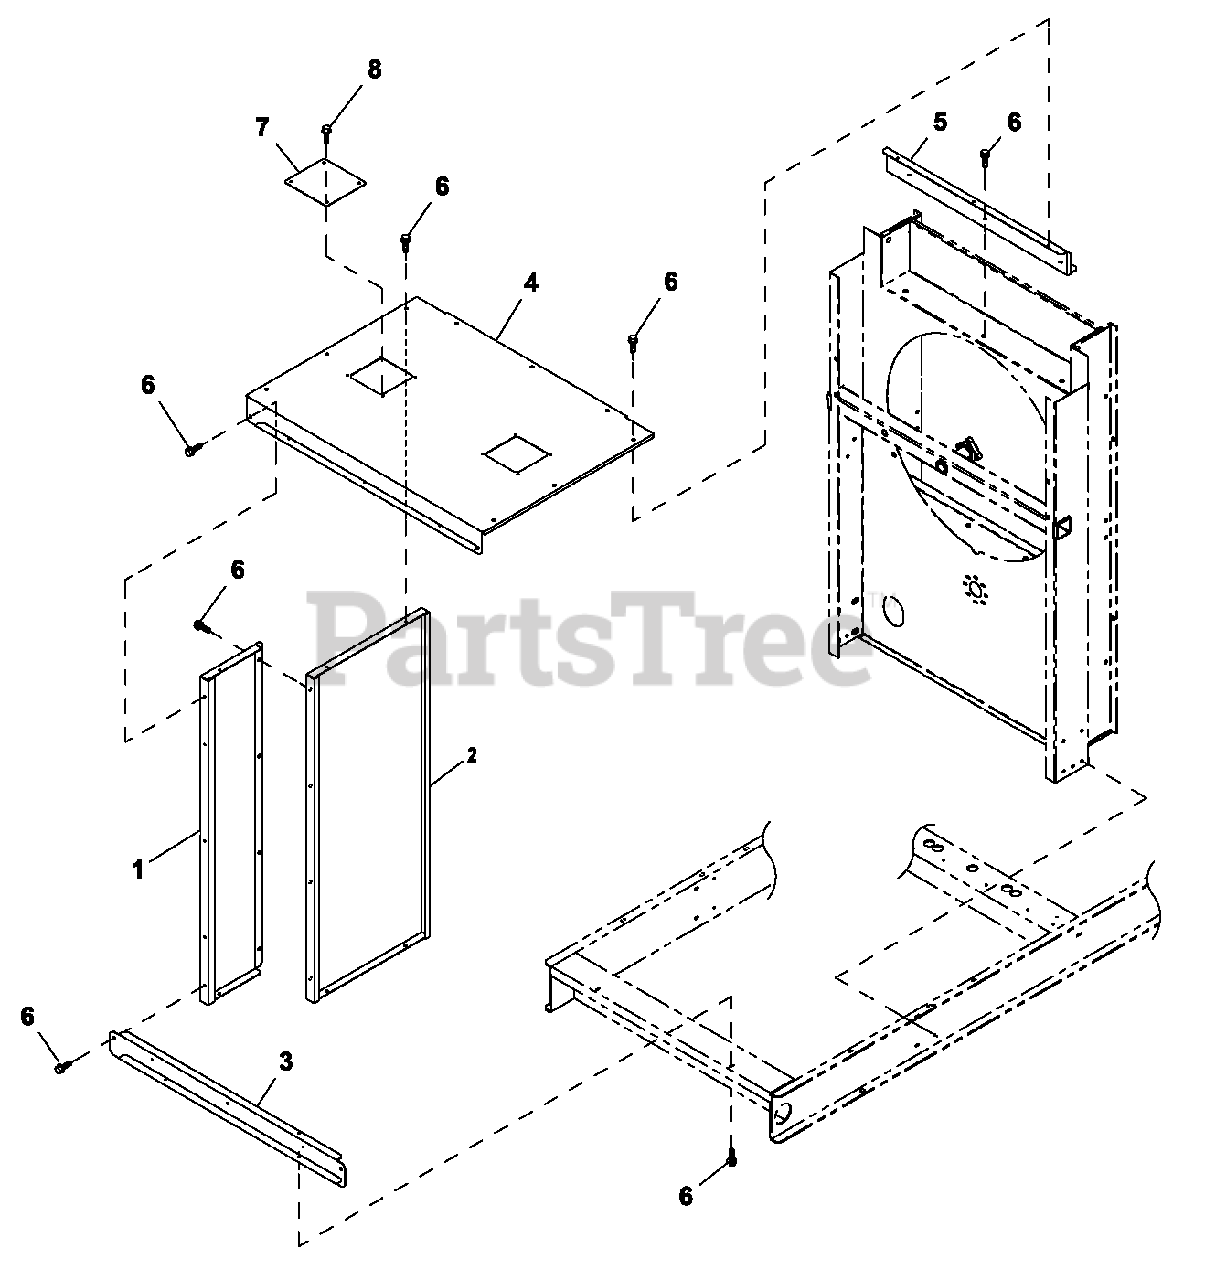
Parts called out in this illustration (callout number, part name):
1	PANEL C5 FRONT SIDES
2	PANEL C5 REAR SIDES
3	PANEL LOWER FRONT
4	PANEL C5 TOP
5	PANEL C5 TOP MOUNT
6	SCREW THF M6-1 X 16 N WAZ/JS
7	ACCESS COVER 160 X 170 GALV
8	SCREW THF M6-1 X 16 N WAZ/JS
